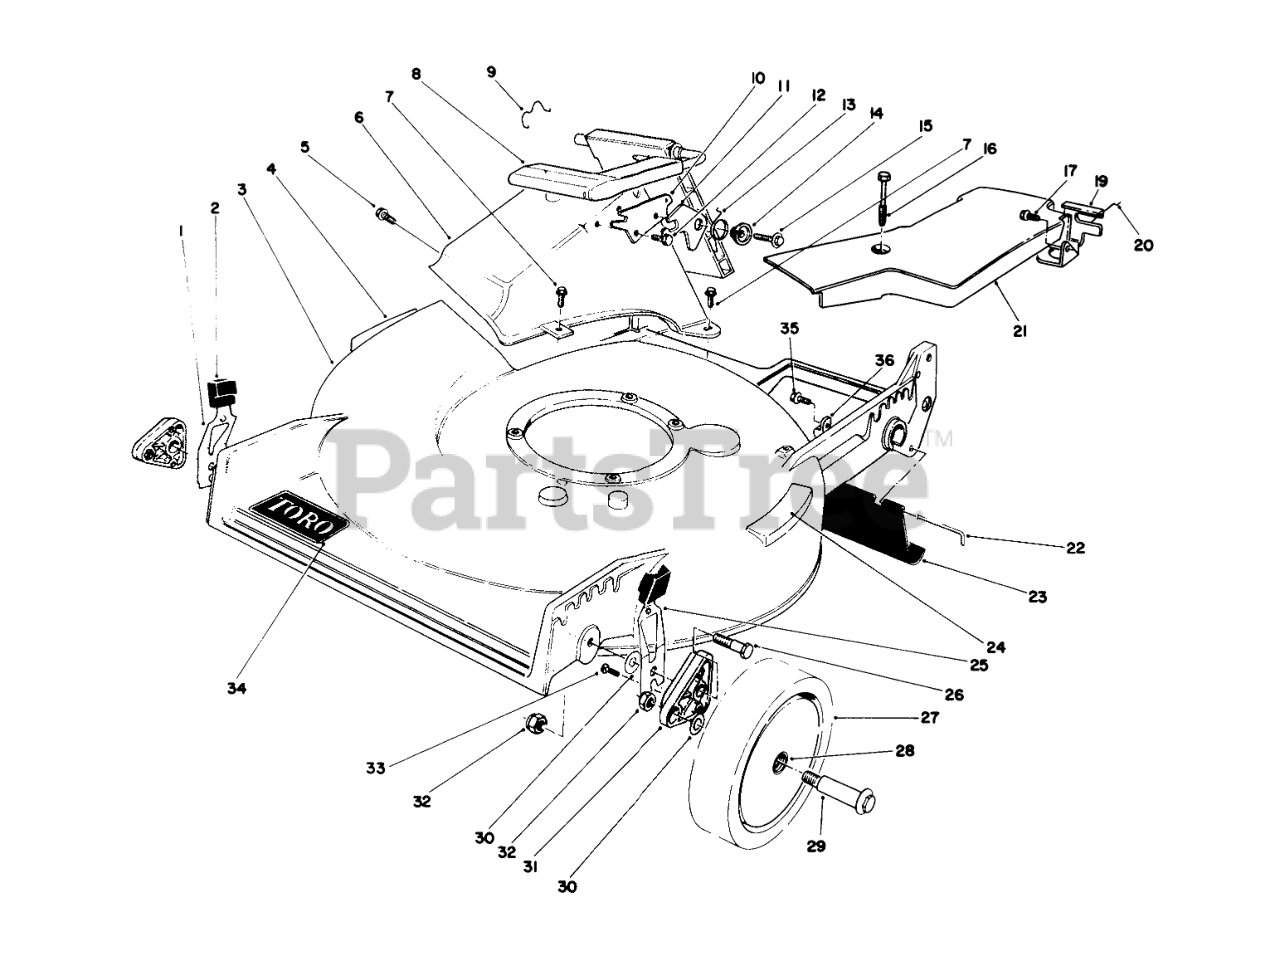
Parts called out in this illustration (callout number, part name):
1	RH SPRING ARM ASSEMBLY
2	KNOB-ARM
3	Housing (Incl. Ref. #4, 7, & 24)
4	DECAL-DANGER
5	SCREW AND WASHER ASM
6	Tunnel-Discharge
7	SCREW-HWH
8	Discharge Door Assembly
9	DOOR RET SPRING
10	DOOR LATCH PLATE
11	SAFETY LATCH
12	SCREW-PLASTITE
13	TORSION SPRING
14	DOOR SPACER
15	SCREW-HWH
16	SCREW-HHFTF
17	SCREW-HWHTF
19	Bracket-Traction Adj.
20	RETAINER-CABLE
21	Cover-Belt
22	ROD-SHIELD
23	SHIELD-TRAILING
25	LH SPRING ARM ASSEMBLY
26	SCREW-SHOULDER
27	Wheel & Tire Assembly (Incl. Ref. #28)
28	BUSHING
29	WHEEL BOLT
30	WASHER
31	ARM-PIVOT, FRONT
32	Nut
33	SCREW-HWH
34	DECAL
35	SCREW
36	CLAMP-CABLE
